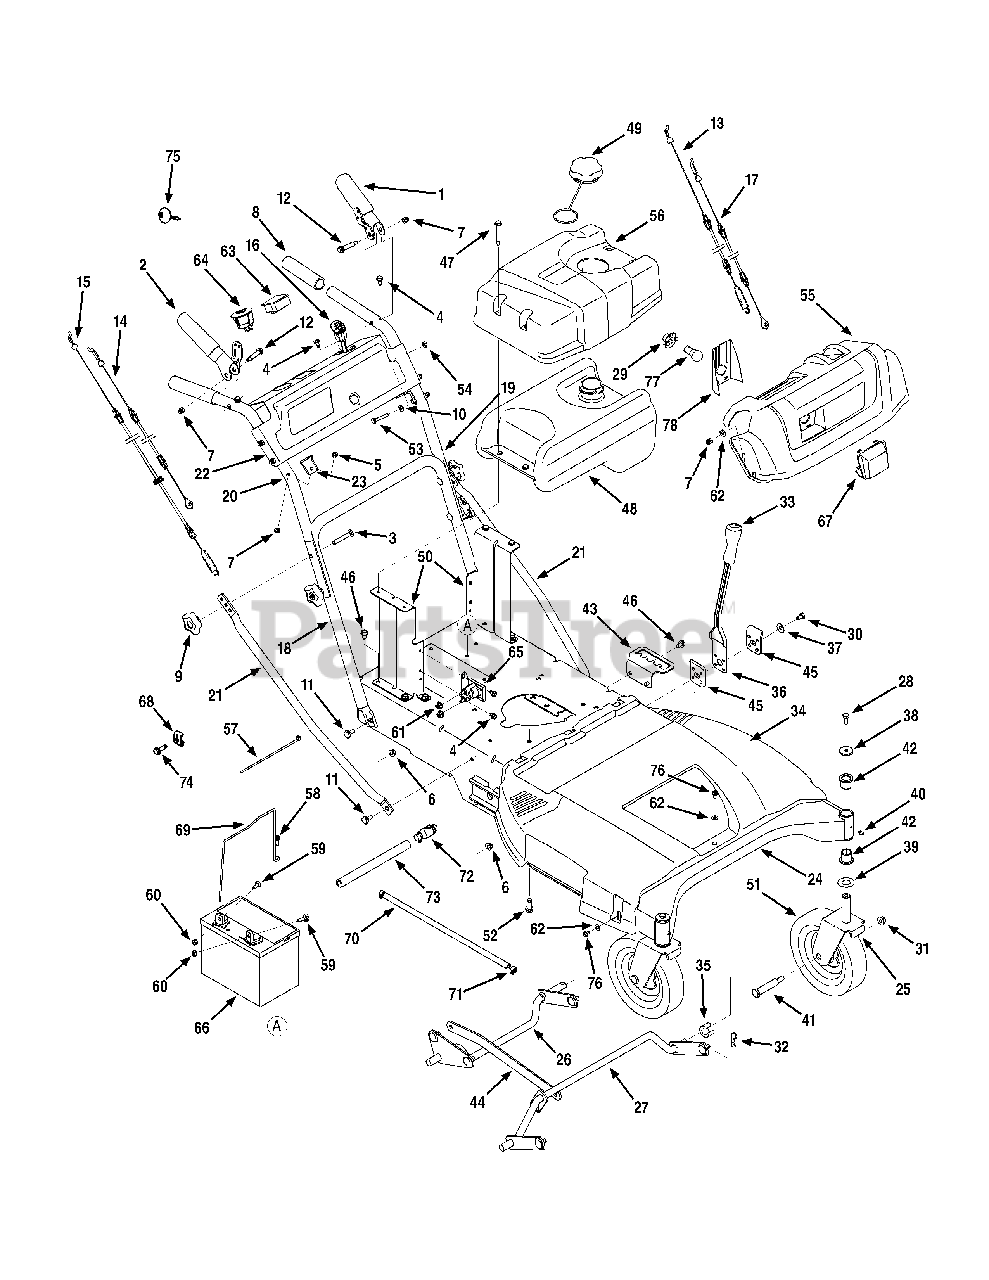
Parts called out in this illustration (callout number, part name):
1	Lever Assembly - LH
2	Lever Assembly - RH
3	Screw, Carriage, 5/16-18 x 2.25
4	Screw, 1/4-20 x 0.500
5	Screw, Cap, 1/4-20 x 1.50
6	Nut, Flange Lock, 5/16-18
7	Nut, Lock Cap, 1/4-20
8	Grip, 1.0 ID x 5.0 Lg
9	Star Knob, 5/16-18
10	Washer, Bell, .265 x .75 x .062
11	Screw, Shoulder, .435 x .178-5/16
12	Screw, Shoulder, .375 x 1.355, 1/4-20
13	Cable, Clutch Wheel
14	Cable, Brake, Transmission - RH
15	Cable, Clutch Deck
16	Cable, Throttle/Choke, 38 x 1.1
17	Cable, Brake, Transmission - LH
18	Lower Handle
19	Upper Handle - LH
20	Upper Handle - RH
21	Brace Tube
22	Handle Panel
23	Cable Mount Bracket - RH
23	Cable Mount Bracket - LH
24	Frame Assembly
25	Caster Wheel Bracket Assembly
26	Deck Lift Assembly, RR
27	Deck Lift Assembly, Front
28	Screw, HH Cap, 5/16-24 x .750
29	Lamp Socket
30	Screw, HH Cap, 5/16-18 x .50
31	Nut, Flange Lock, 3/8-16
32	Click Pin, .092 x 1.64
33	Handle Grip
34	Belt Cover
35	Snap Spacer, .63 ID x .75 LG
36	Deck Height Lever
37	Washer, Bell, .340 x .872 x .060
38	Washer, Flat, .330 x 1.25 x .120
39	Washer, Flat, .760 ID x 1.50 OD
40	Lube Fitting, 3/16
41	Bolt, Shoulder, .625 x 2.515 x 3/8-16
42	Flange Bearing, .760 x .941 x 1.0
43	Height Adjustment Bracket
44	Link Pivot Bracket
45	Lever Pivot Bracket
46	Screw, TT, 5/16-18 x .625
47	Screw, Shoulder, .32 x 1.8 x 1/4-20
48	Fuel Tank, 2 Gal.
49	Fuel Cap
50	Fuel Tank Mounting Bracket
51	Wheel, 8 x 1.75
52	Screw, TT, 3/8-16 x 1.25
53	Screw, HH Cap, 1/4-20 x 1.75
54	Nut, Hex, 1/4-20
55	Handle Panel
56	Tank Cover
57	Cable Tie
58	Screw, TT, 1/4-20 x .75
59	Screw, 1/4-20 x .75
60	Nut, Sems, 1/4-20
61	Nut, Flange Lock, 1/4-20
62	Washer, Flat, .25 x .63 x .0515
63	Hour Indicator Meter
64	Key Switch
65	Solenoid, 12V
66	Battery
68	Casing Clamp
69	Battery Hold Down
70	Fuel Hose
71	Hose Clamp
72	Oil Drain
73	Oil Drain Hose
74	Screw, 10-32 X .625
75	Key, Ignition, Black
76	Screw, 1/4-20 x 1.75
77	Lamp
78	Label Reflector
